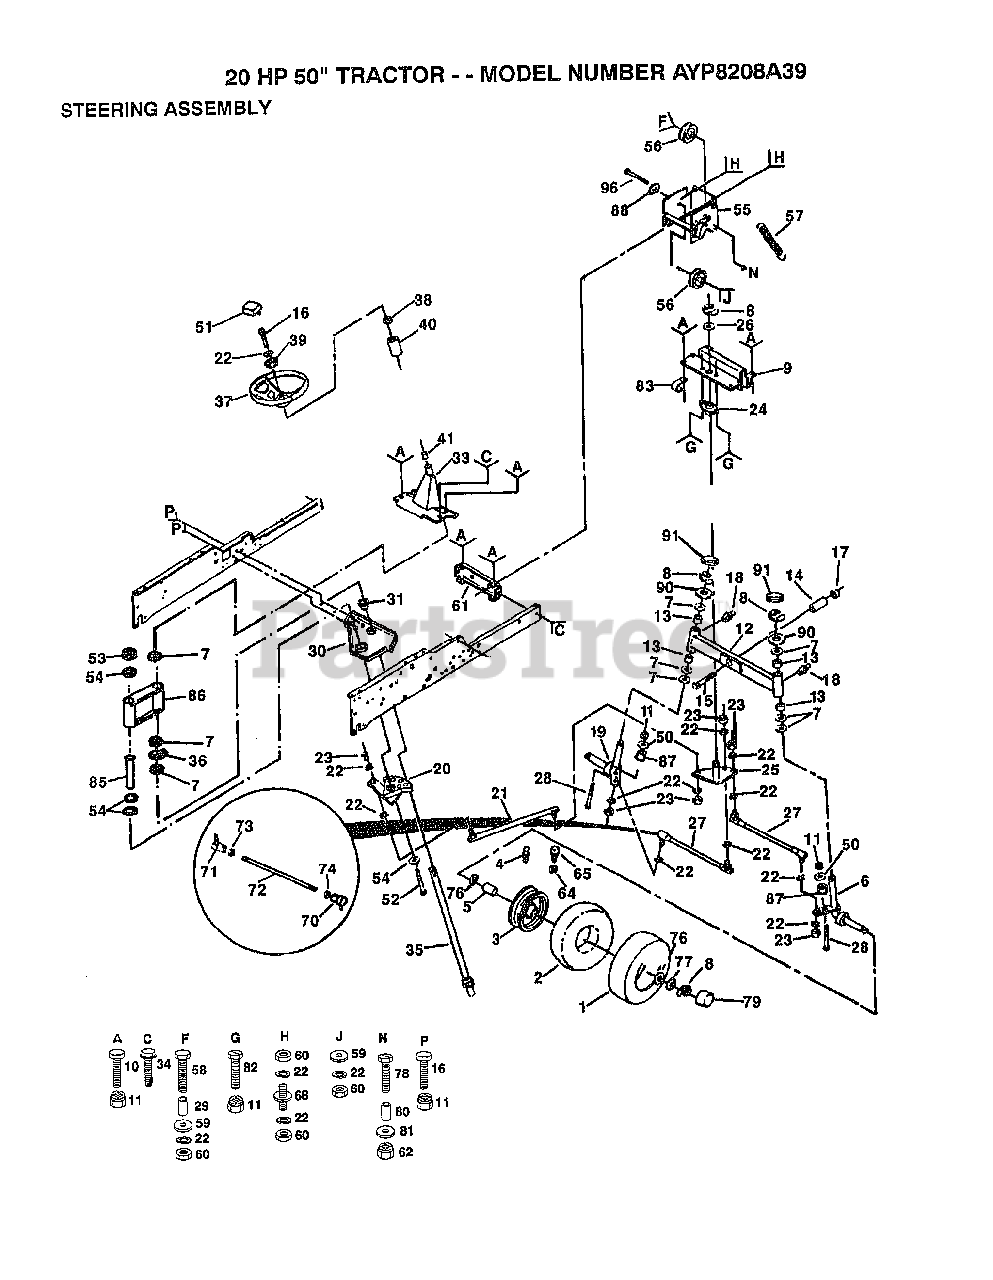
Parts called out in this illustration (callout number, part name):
2	TUBE.16X6.5/7.5-8
4	FITTING LT
5	"FLANGE, BEARING"
6	SPINDLE RH T
7	WASHER .T
8	RING
9	AXLE BRACKET T
12	AXLE ASSEMBLY
13	BRNG. T
14	SPACER BEARING
15	BOLT
16	BOLT
17	LOCKNUT M
18	ZERK M
19	SPINDLE ASSY T
20	SECTOR T
21	LINK.DRAG.T
22	LOCKWASHER
25	"T, BELLCRANK"
26	WASHER
27	TIE ROD T
28	BOLT
29	SPLIT SPACER YTV
31	"FLANGE GT, BEAR."
33	SUPPORT ASSY T
34	SCREW
35	SHAFT ASSY GT
36	KLIP RING
38	ADAPTER LT
39	WASHER T
40	SLEEVE LTV
41	"T, BEARING"
50	WASHER T
51	ST WHL INSERT CAP
52	BOLT T
53	NUT LTV
54	WASHER GT
55	IDLER BRKT T
56	IDLER-INSIDE T
57	SPRING
58	BOLT
59	WASHER
60	NUT.HEX.3/8-16UNC
61	FRAME BRACKET GT
64	VALVE STEM LT
65	VALVE CAP
70	JOINT.RH
71	JOINT.LH
73	NUT
74	NUT
76	WASHER
77	WASHER
79	HUB CAP
80	BUSHING LT
81	WASHER
82	BOLT
83	CLIP GTV
85	TUBE T
86	COLLAR
87	SPACER LT
88	WASHER T
90	WASHER
91	CAP
